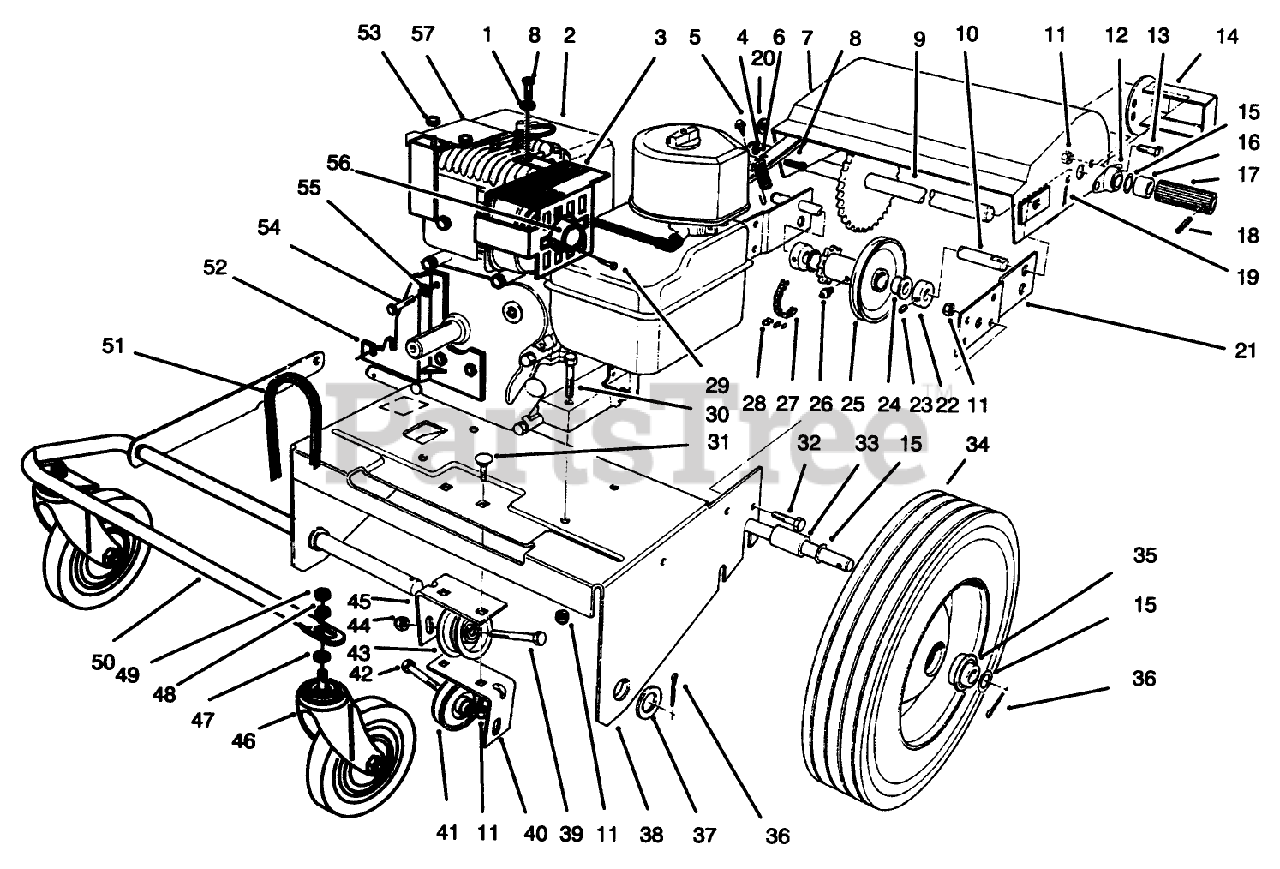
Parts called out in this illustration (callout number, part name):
1	WASHER-BELLEVILLE
3	SHIELD-MUFFLER
4	NUT-LOCK, NI
5	SCREW-HH
6	SPRING-TRACTION
7	Guard
8	SCREW-HH
9	SHAFT-WHEEL, FRICTION
10	SHAFT-IDLER
11	NUT-LOCK, NI
12	BEARING-MOUNT, FLANGE
13	SCREW-HH
14	Guard
15	WASHER
16	SPACER
17	WHEEL-FRICTION
18	PIN-ROLL, SLOTTED
19	PIN-COTTER
20	WASHER-FLAT
21	Bracket Mounting
22	Collar (Incl. Ref. #23)
23	1/4-20X1/4 HEX SOC SS
24	BUSHING-FLANGE
25	Idler Assembly (Incl. Ref. #24 & 26)
26	FITTING-GREASE
27	Chain (Incl. Ref. #28)
28	LINK-CONNECTING, NO. 35
29	SCREW - 94126 F/W
30	SCREW-HH
31	SCREW-CARR
32	SCREW-HH
33	SPACER-AXLE
34	Wheel (Incl. Ref. #35)
35	BEARING
36	PIN-COTTER
37	WASHER-FLAT
38	Engine Plate
39	SCREW-HH
40	Bracket-Idler Mount L.H.
41	PULLEY-IDLER
42	SCREW-HH
43	PULLEY-IDLER
44	NUT-LOCK, NI
45	Bracket-Idler Mount R.H.
46	CASTER
47	WASHER-LOCK/INT
48	NUT-HH
49	NUT-LOCK, NI
50	Support-Front Wheel
51	BELT-V
52	Guard
53	NUT-LOCK, NI
54	SCREW-HH
55	WASHER-LOCK
56	WA - EXHAUST EXTENSION
57	MTG BRKT WA B
